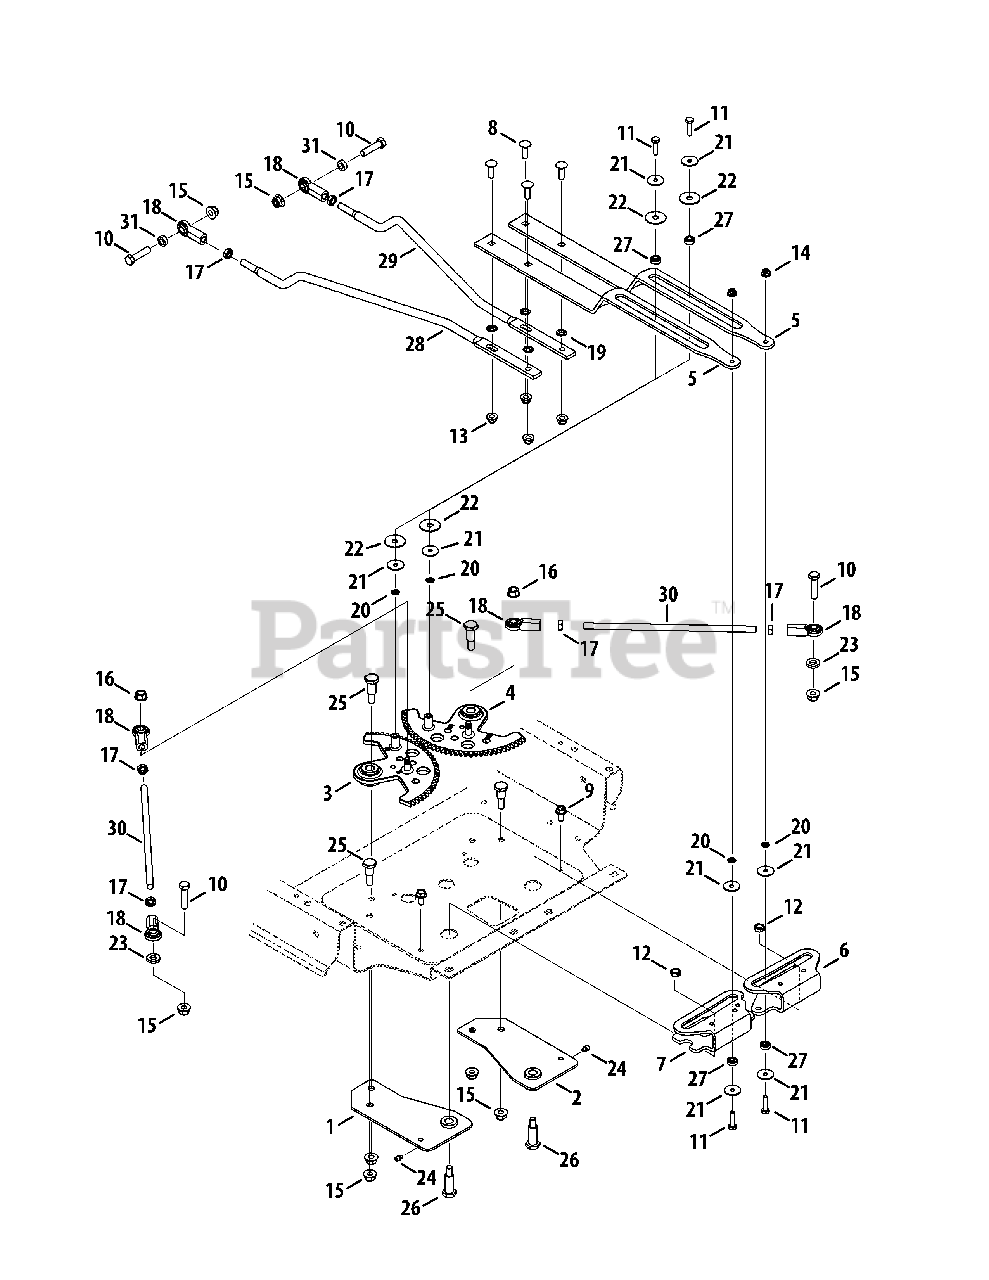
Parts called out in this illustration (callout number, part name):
1	Steering Plate Assembly, RH
2	Steering Plate Assembly, LH
3	Steering Gear Assembly, RH
4	Steering Gear Assembly, LH
5	Control Link
6	Speed Cam Plate, LH
7	Speed Cam Plate, RH
8	Carriage Screw, 5/16-18 x 1.00
9	Hex Washer Screw, 5/16-18 x .750
10	Hex Screw, 3/8-16 x 1.50
11	Hex Screw, 1/4-20 x 1.00
12	Nut, Jamlock, 3/8-16
13	Flange Lock Nut, 5/16-18
14	Flange Lock Nut, 1/4-20
15	Flange Lock Nut, 3/8-16
16	Nut, 5/16-18, Centerlock
17	Jam Nut, 3/8-24
18	Female Ball-Joint
19	Speed Nut, .3125 ID
20	Push Nut, .25 ID x .50 OD
21	Flat Washer, .285 x 1.25 x .060
22	Washer, .355 x 1.25 x .048
23	Flat Washer, .407 x .812 x .135
24	Grease Fitting, 3/16
25	Shoulder Screw, 3/8-16 x .625 x .875
26	Shoulder Screw, .500 x 1.25 x 3/8-16
27	Ball Bearing, .25 x .625
28	Hydro Link, RH
29	Hydro Link, LH
30	Drag Link, .375 Dia.
31	Spacer, .380 ID x .625 OD x .21
